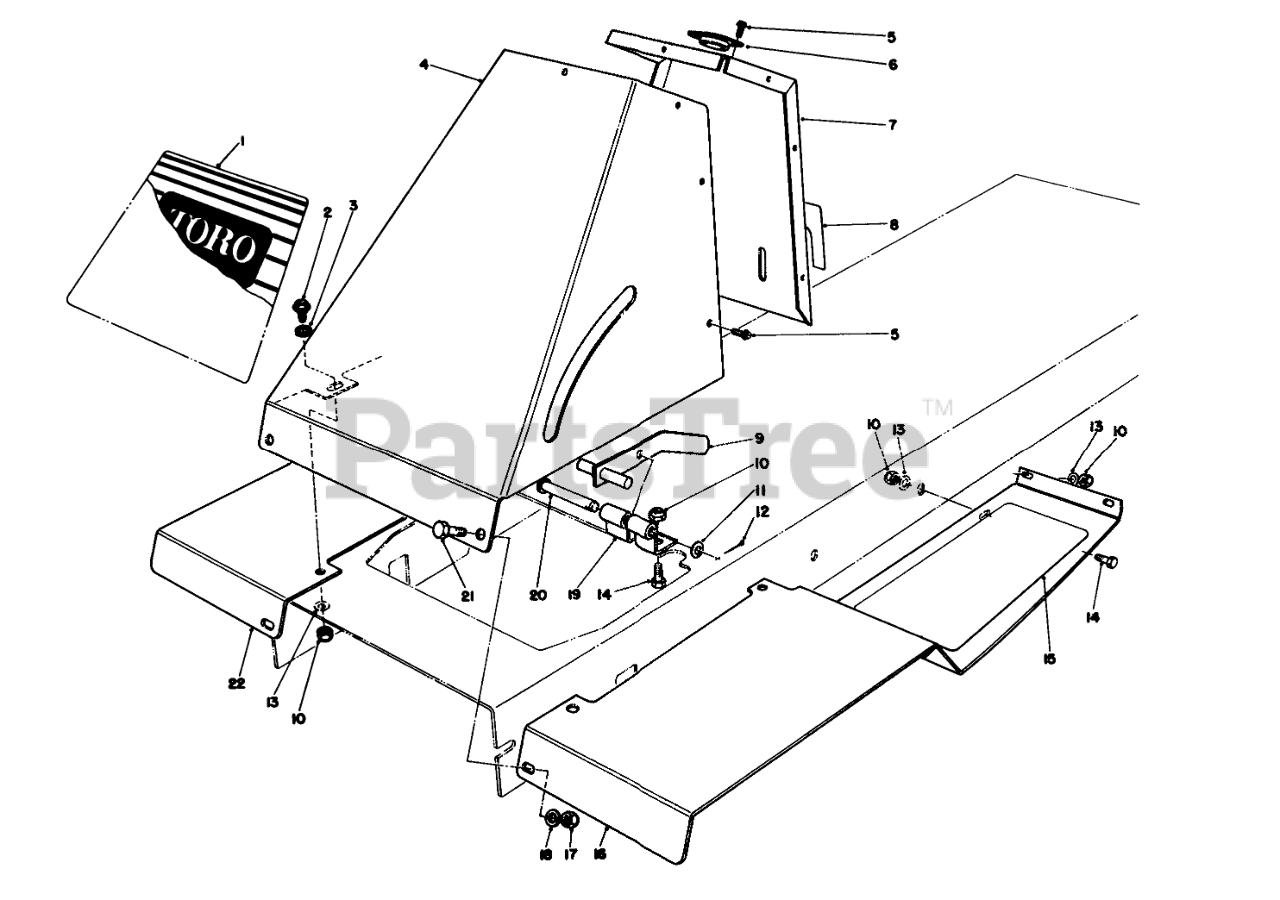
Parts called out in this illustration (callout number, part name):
1	DECAL - TORO 832 PRO
2	SCREW-SHOULDER
3	SPACER
4	Tower-Front
5	SCREW-HWHTF
6	GUIDE-STRG SHAFT
7	Tower-Rear
8	PARK BRAKE DECAL
9	PARKING BRAKE WA B
10	NUT-LOCK, NI
11	WASHER-FLAT
12	PIN-COTTER
13	WASHER-PLAIN
14	SCREW-HH
15	FOOT TREAD L.H.
16	Footrest-LH
17	NUT-LOCK, CONE
18	WASHER-FLAT
19	Bracket-Parking Brake
20	PIN-CLEVIS
21	SCREW-HH
22	Footrest-RH.
